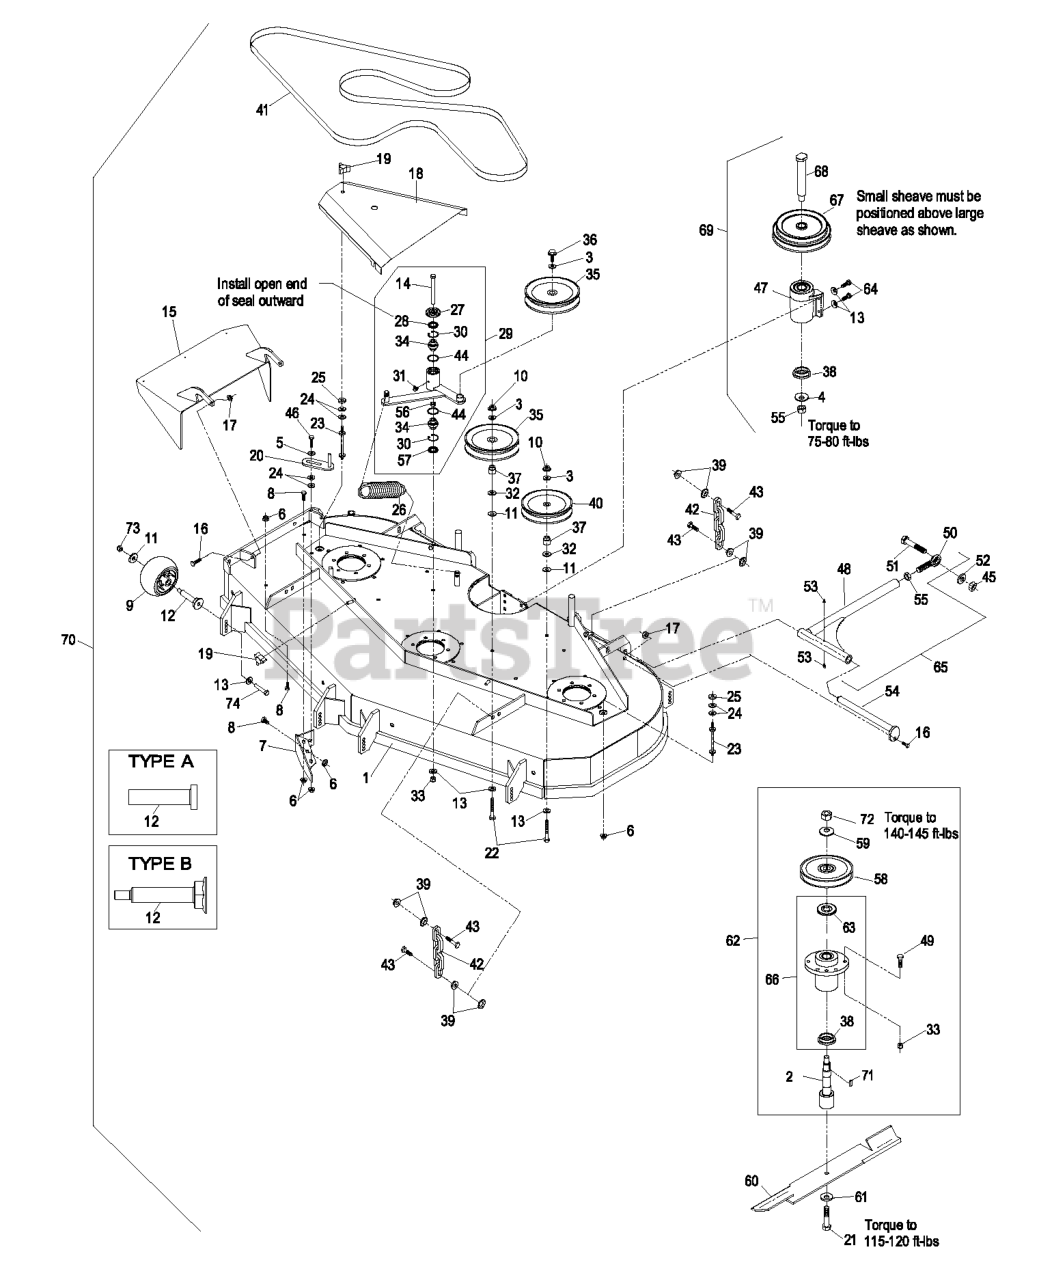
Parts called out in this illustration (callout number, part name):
1	ASM,DECK W/DECALS XP604
2	SPINDLE,SHORT
3	WASHER-FLAT
4	WASHER-SPRING
5	WASHER-SPRING
7	WLD,BAFFLE DISCHARGE
8	SCREW-HH
9	ROLLER-SCALP, ANTI
10	NUT-HHF, WHIZ
12	BUSHING-ROLLER
13	WASHER-BELLEVILLE
14	SCREW-HH
15	WLD,CHUTE XP604
16	SCREW-HH
17	NUT-LOCK, NI
18	SHIELD,BELT
19	KNOB-3 PRONG
20	GUIDE-BELT
21	SCREW-CAP
22	SCREW-HH
23	STUD-SHIELD, BELT (SHORT)
24	WASHER-FLAT
27	GUARD-TOP
28	SEAL-LIP, SINGLE
29	KIT,DECK IDLER LZ/XP
30	RING-SNAP
31	FITTING-GREASE, 90 DEG
32	WASHER-FLAT
33	NUT-LOCK, NI
34	BEARING-SPHERICAL
36	SCREW-HHF
37	BUSHING-IDLER
38	SPACER-GUARD, BOTTOM
40	PULLEY-IDLER
41	BELT,BLADE DRIVE
42	CHAIN-LIFT, DECK
43	SCREW-HH
45	NUT-HEX
46	SCREW-HH
49	SCREW-HH
50	BALLJOINT-SPHERICAL
51	SCREW-HH
52	WASHER-LOCK
53	FITTING-GREASE
54	PIN-STRUT
55	NUT-HEX
57	SEAL-LIP, DOUBLE
58	SHEAVE,BLADE DRIVE 6.30
61	WASHER-BLADE BOLT, HEAVY
62	ASM, CUTTER HSG COMPLETE
63	GUARD-BEARING, TOP
64	SCREW-HH
65	STRUT ASM
66	KIT, CUTTER HOUSING
67	SHEAVE, JACKSHAFT DOUBLE
68	JACKSHAFT
69	KIT,JACKSHAFT 60/72-3750
70	Asm, Deck Complete
72	NUT-HH
73	NUT-HHF, WHIZ
74	SCREW-HH
